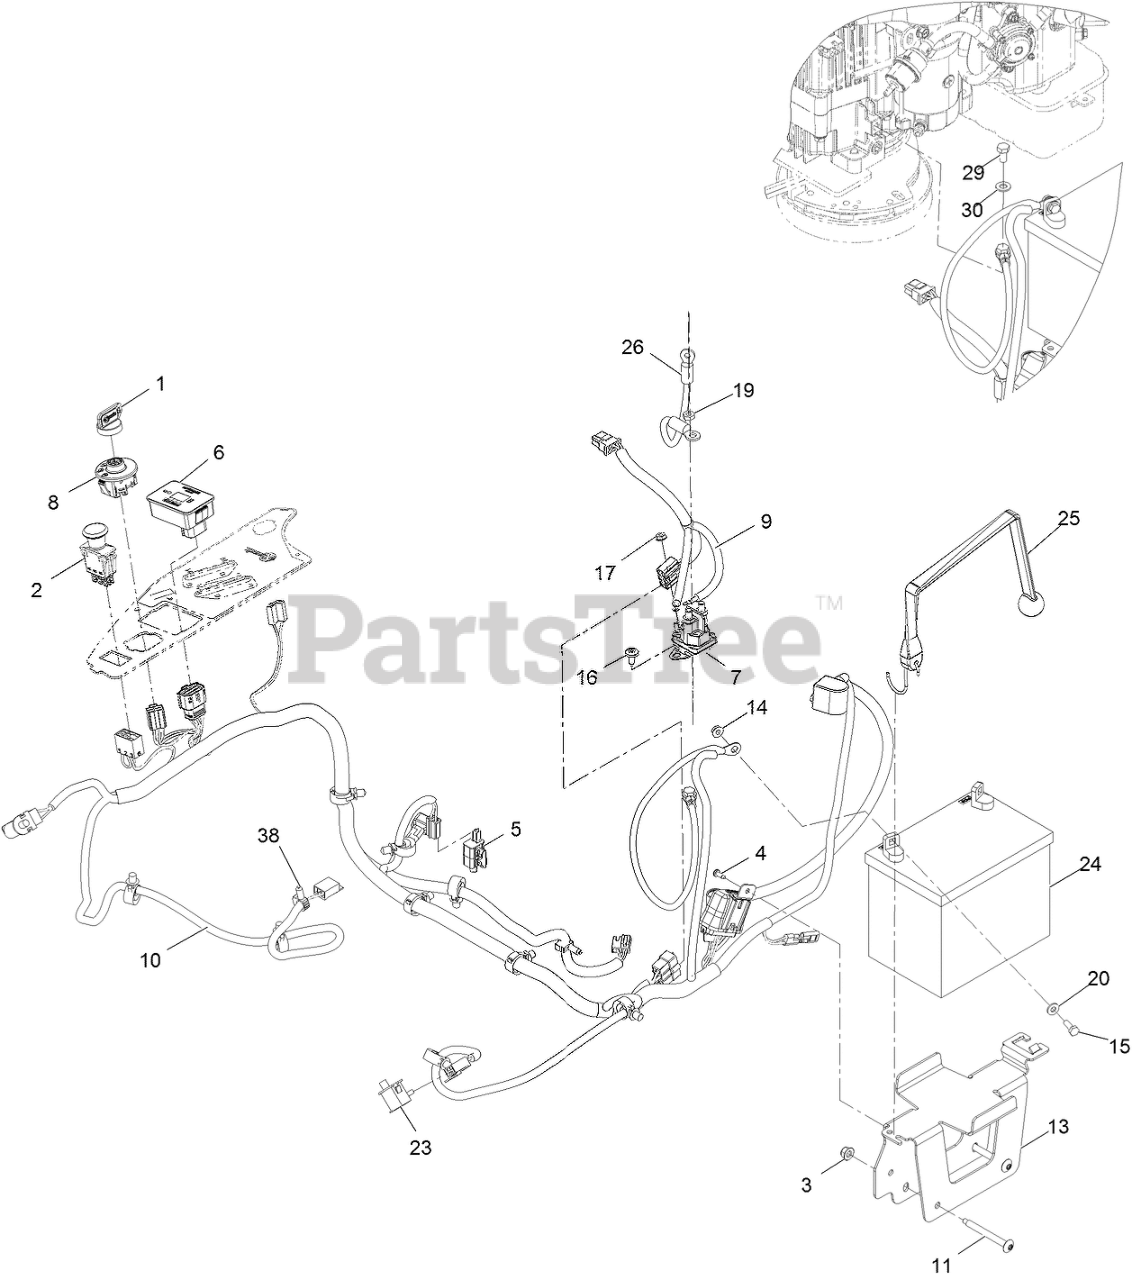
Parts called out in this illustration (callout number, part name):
1	KEYS-IGNITION (SPARE PAIR
1	KEY-IGNITION
2	SWITCH-PTO
3	NUT-HF, NI
4	SCREW-FORMING, THREAD
6	MODULE ASM
7	SOLENOID
8	SWITCH-IGNITION
9	ADAPTER-HARNESS, WIRE
10	HARNESS-WIRE
11	SCREW-TORX
13	TRAY-BATTERY
15	SCREW-HH
16	SCREW-TORX
17	NUT-KEPS
19	NUT-JAM
20	WASHER-FLAT
23	SWITCH-BAIL
24	Battery
25	STRAP-BUNGEE
26	CABLE-BATTERY, POSITIVE
29	SCREW-HH
30	WASHER-PLAIN
38	CLIP-HARNESS
